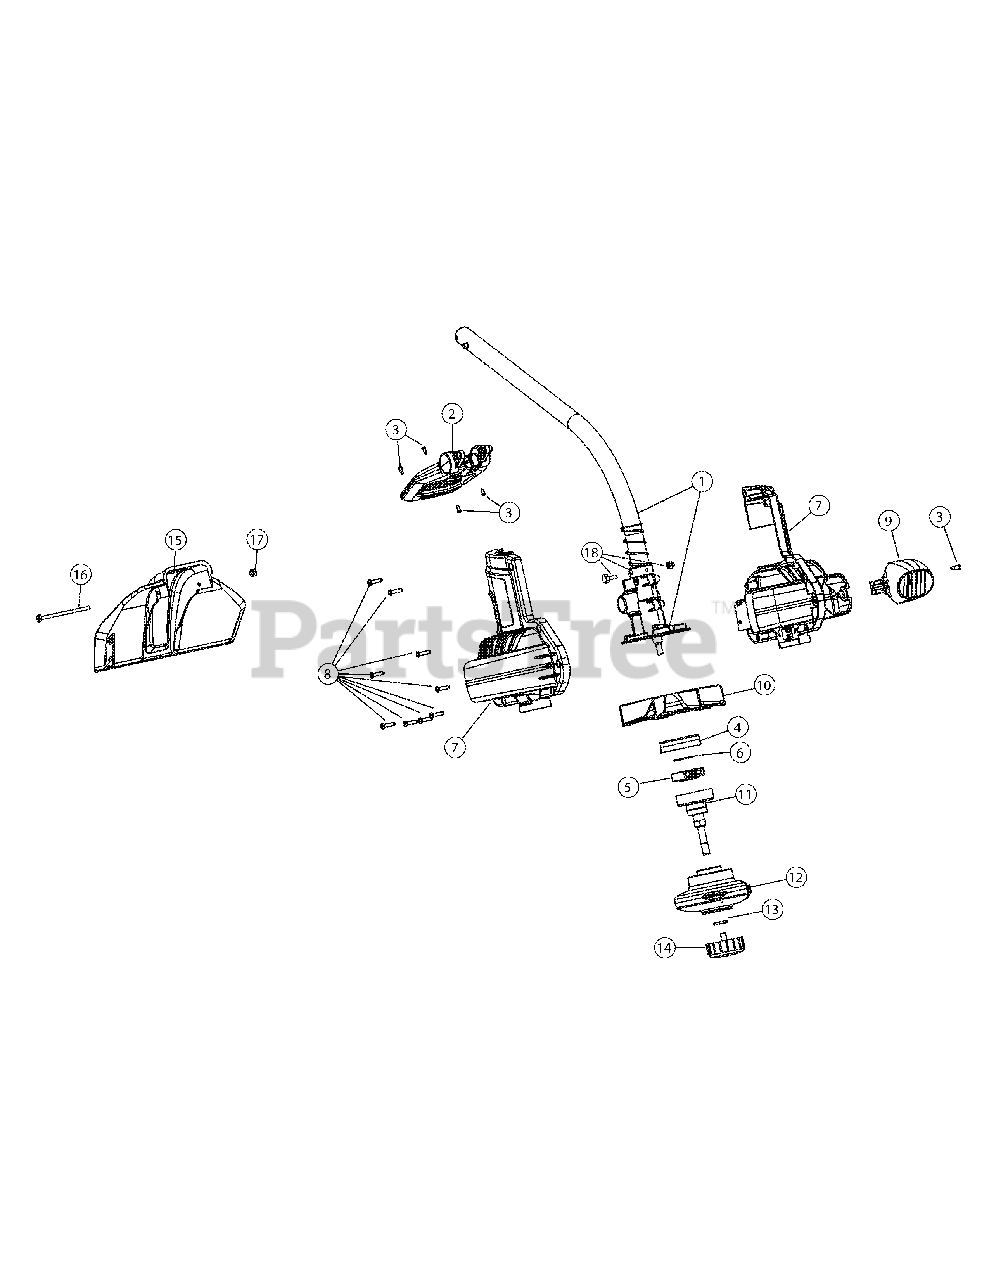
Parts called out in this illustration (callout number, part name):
1	Lower Drive Shaft Housing Assembly
2	Shift Handle Assembly
3	Screw
4	Clutch Drum Container
5	Clutch Assembly
6	Washer
7	Housing Assembly
8	Screw
11	Clutch Drum Assembly w/Spool Shaft
12	Fixed Line Head
13	Washer
14	Bump Knob Assembly
15	Guard Assembly w/Blade
16	Screw
17	Nut
